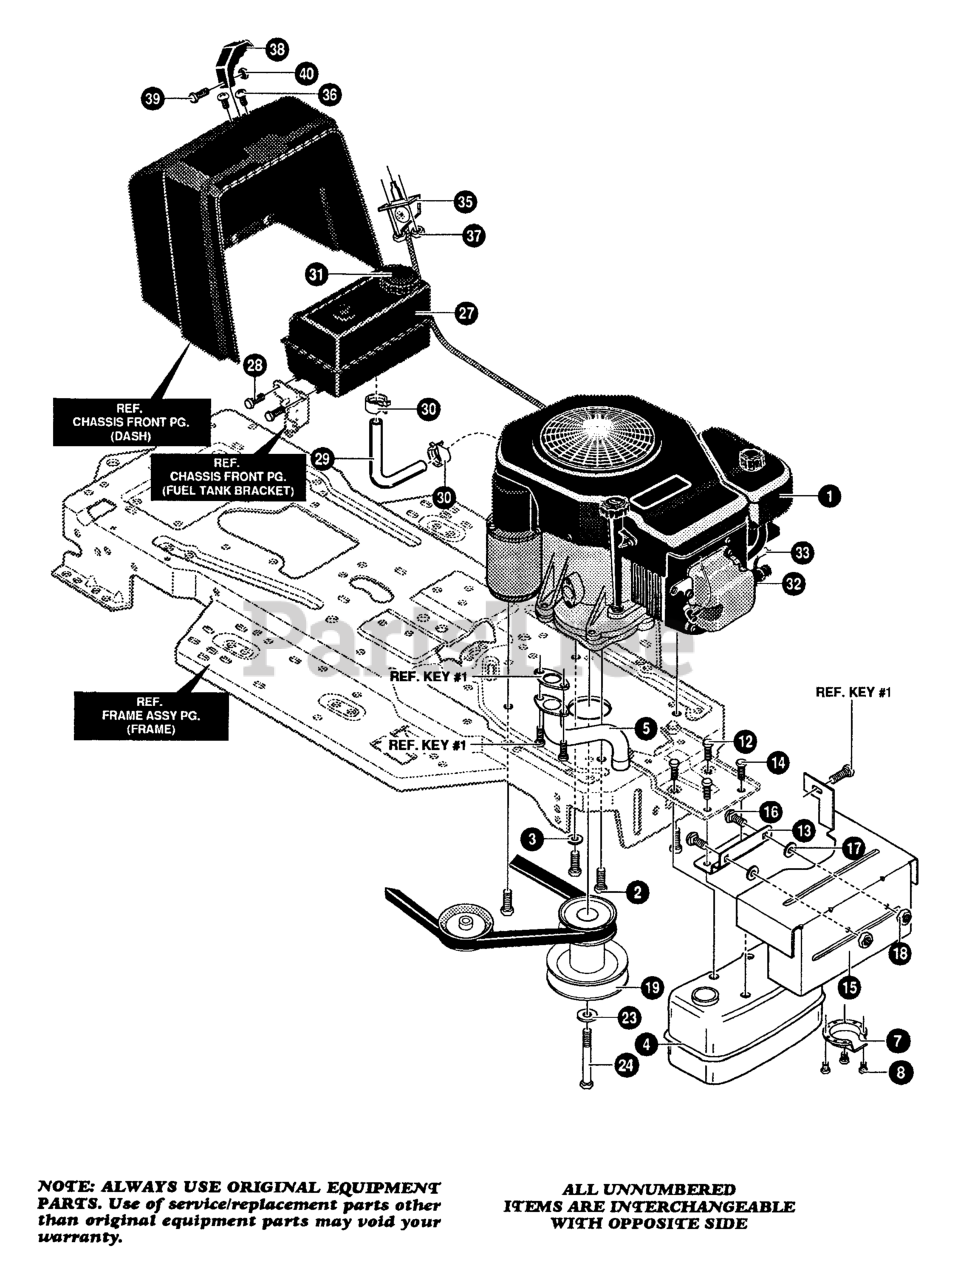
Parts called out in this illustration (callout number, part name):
1	ENGINE, 12-15HP KOHLER
2	SCREW, 1.25 x 25
3	WASHER, .320 x .61 x .03
4	MUFFLER
5	TUBE, MUFFLER EXHAUST
7	DEFLECTOR SIDE OUT
8	SCREW, #8-32 x .38
12	SCREW, 1/4-20 x .88
13	BRACKET, TRANSAXLE
14	SCREW, 1/4-20 x .75
15	ASSEMBLY, SHIELD HEAT
16	BOLT, 5/16-18 x .63
17	PUSHNUT, BOLT RETAINER
18	NUT, 5/16-18
19	PULLEY, ENGINE
23	WASHER, .459 x .78 x .12
24	SCREW, 7/16-20 x 5.00
27	TANK, FUEL 1.5
28	SCREW, .25 x .75 x .5
29	TUBING, GAS LINE
30	CLAMP, HOSE SCREW TYPE
31	CAP, FUEL
32	OIL DRAIN VALVE ASSEMBLY
33	CAP, OIL DRAIN VALVE
35	THROTTLE CONTROL
36	SCREW, 10-24 X .63
37	NUT, #10-24
38	KNOB, THROTTLE CONTROL
39	SCREW, #8-32 x .38
40	NUT, #8-32
